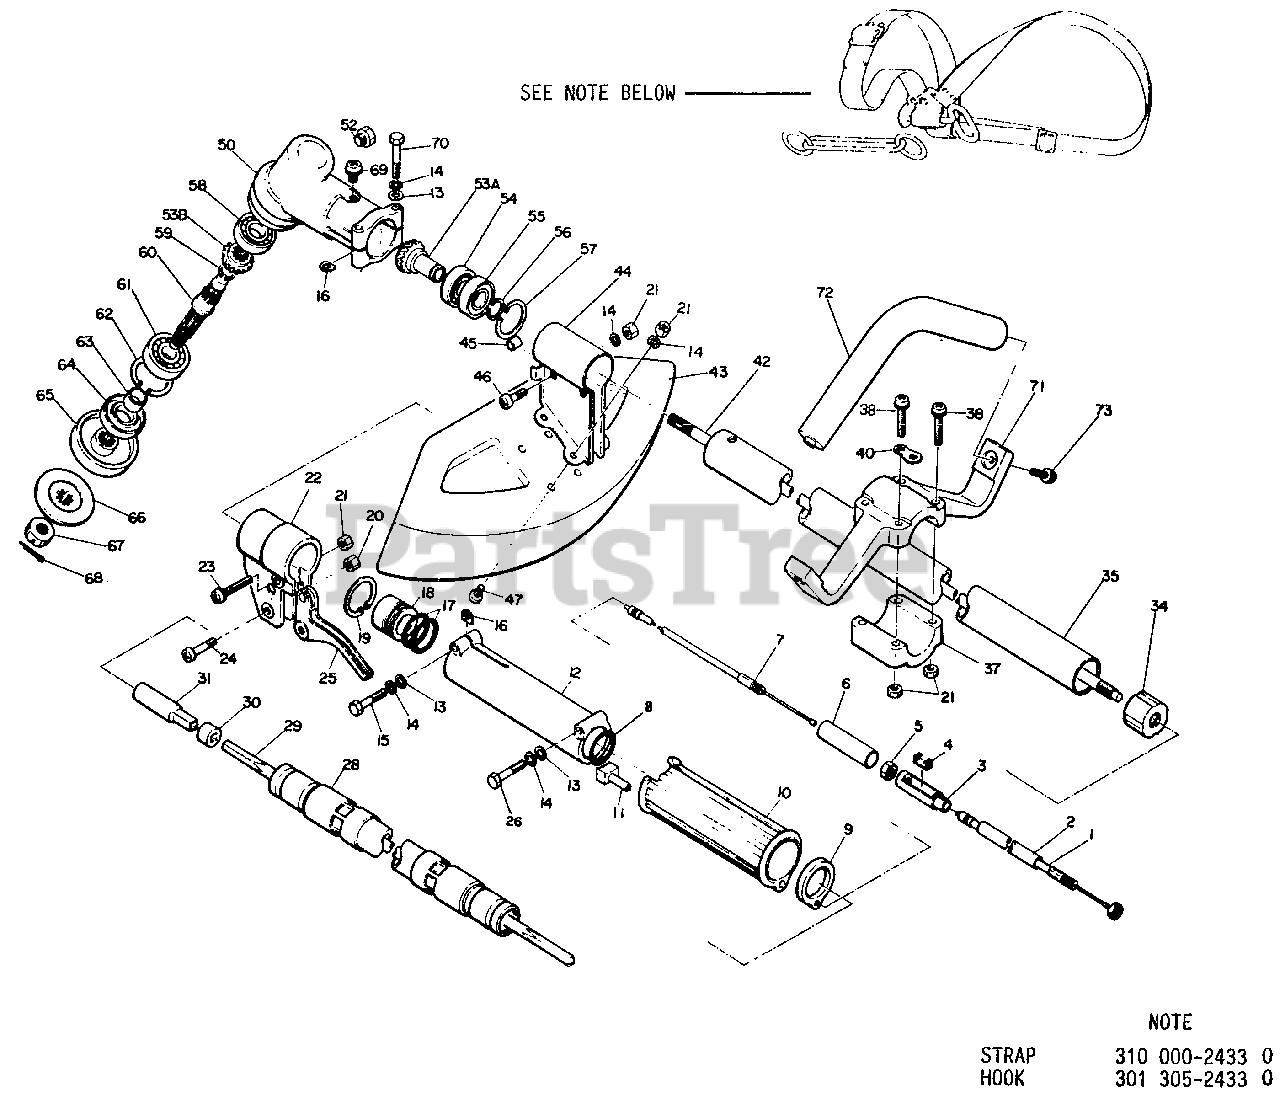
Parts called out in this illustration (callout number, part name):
1	CABLE, THROTTLE
2	SLEEVE
3	CONNECTOR
4	CONNECTOR
6	SLEEVE, JOINT RETAINER
7	CABLE, THROTTLE
8	O-RING 18
10	GRIP
11	GUIDE, CABLE
12	CONNECTOR
13	WASHER, FLAT 5.5×10×0.8
14	WASHER, SPRING 5
14	LOCKWASHER - 3
15	BOLT - 5×25
17	O-RING 22
18	STOPPER
19	RING, SNAP 28
20	LOCKNUT - 5
21	NUT M5
22	BRACKET, TRIGGER
23	SCREW 5×28
25	TRIGGER, THROTTLE
28	LINER, FLEXIBLE
29	DRIVESHAFT - FLEXIBLE
30	SPACER
31	CONNECTOR
34	BUSHING
35	MAIN PIPE ASSY
37	BRACKET, HANDLE
38	SCREW 5×35
40	HANGER
41	HARNESS ASSY
42	DRIVESHAFT
44	BRACKET
45	SPACER, GUARD
46	SCREW 5×18
47	SCREW - 5×8
50	HOUSING, GEAR CASE
52	BOLT 8×8 SP
53	GEAR SET
53A	GEAR SET
53B	GEAR SET
54	BEARING, BALL 6001
55	BEARING, BALL 6001
56	RING, RETAINING - 12
57	RING, SNAP 28
58	BEARING, BALL 6000
59	RING, RETAINING - 12
60	SHAFT, GEAR
61	BEARING, BALL - 6201 C3
62	RING, SNAP Ø32
63	SPACER 11.8×15×9
64	SEAL, OIL 22
65	PLATE, ADAPTER - UPPER
66	PLATE, ADAPTER - LOWER
67	NUT - 10 -- LEFT HAND
68	PIN, COTTER 2×22
69	SCREW 5×10
70	BOLT 5×30
71	BRACKET, HANDLE
72	HANDLE
73	SCREW 5×14
30130524330	HOOK
31000024330	STRAP (OBSOLETE)
